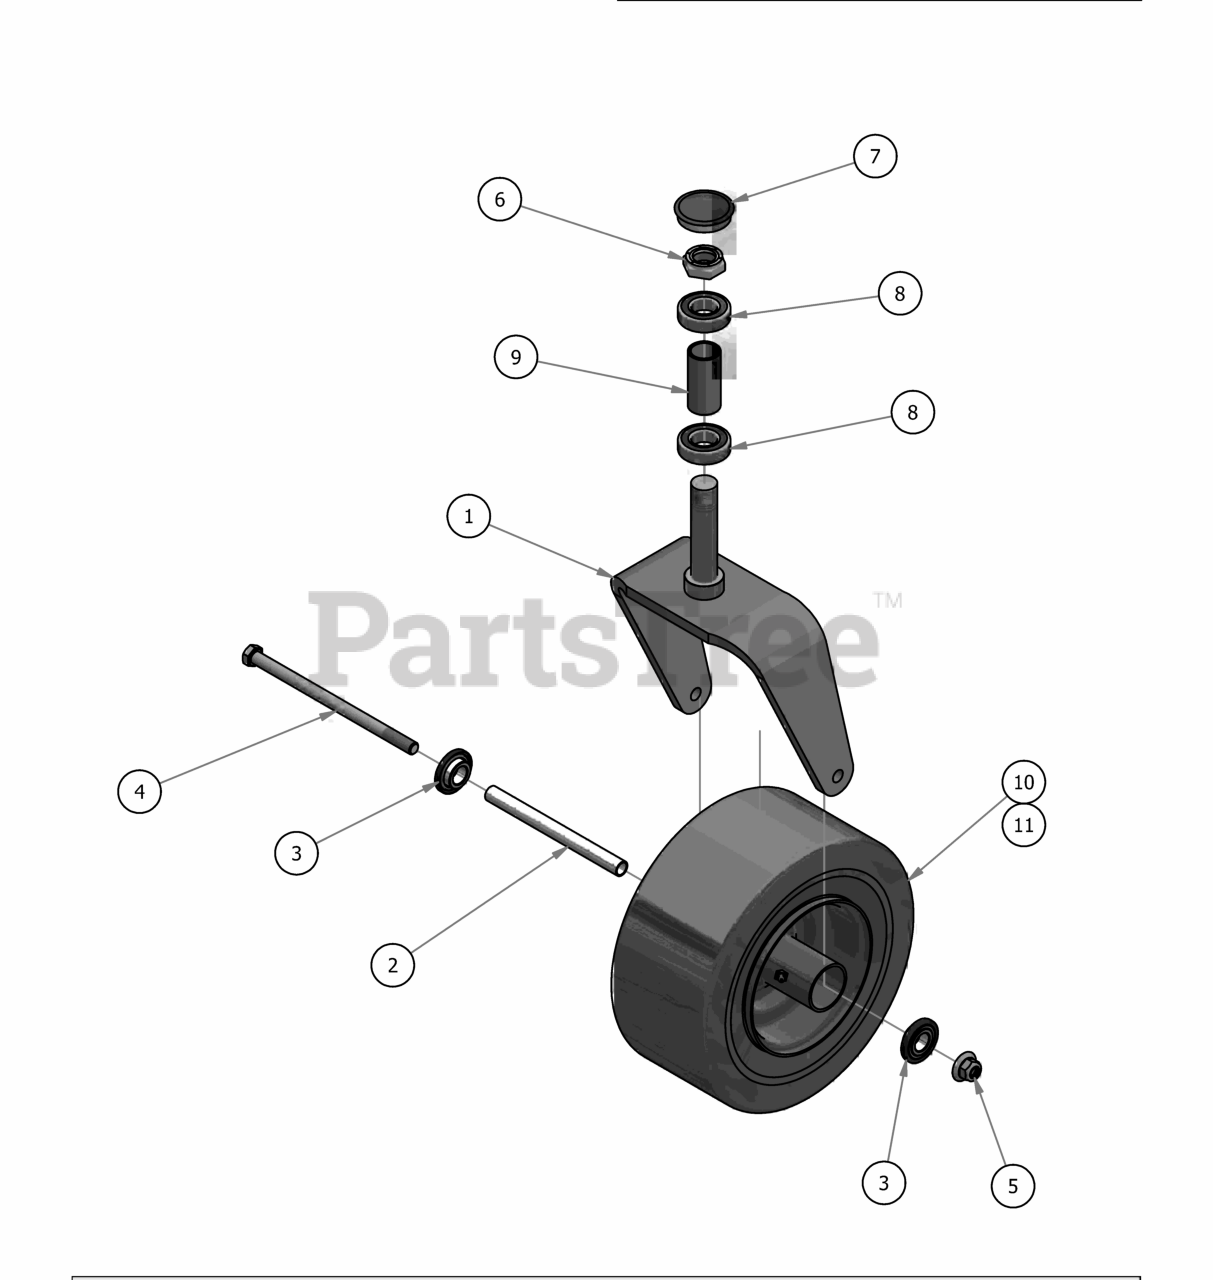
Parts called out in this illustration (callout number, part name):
1	Front Fork
2	Front Wheel Spanner
3	1-3/4" Bearing-Large Bore
4	1/2" x 9" GR 5 Hex Bolt
5	1/2-13 Nylon Flange Nut
6	1" Fine Thread 1/2 Nylock Nut
7	2017 Bearing Cover
8	Caster Bearing 2016 - 1641 Bearing
9	2016 Front Bearing Spacer
10	Tire and black wheel assembly (Parts: 2,3,& 11)
11	13 x 6.50 - 6 Tire Only
